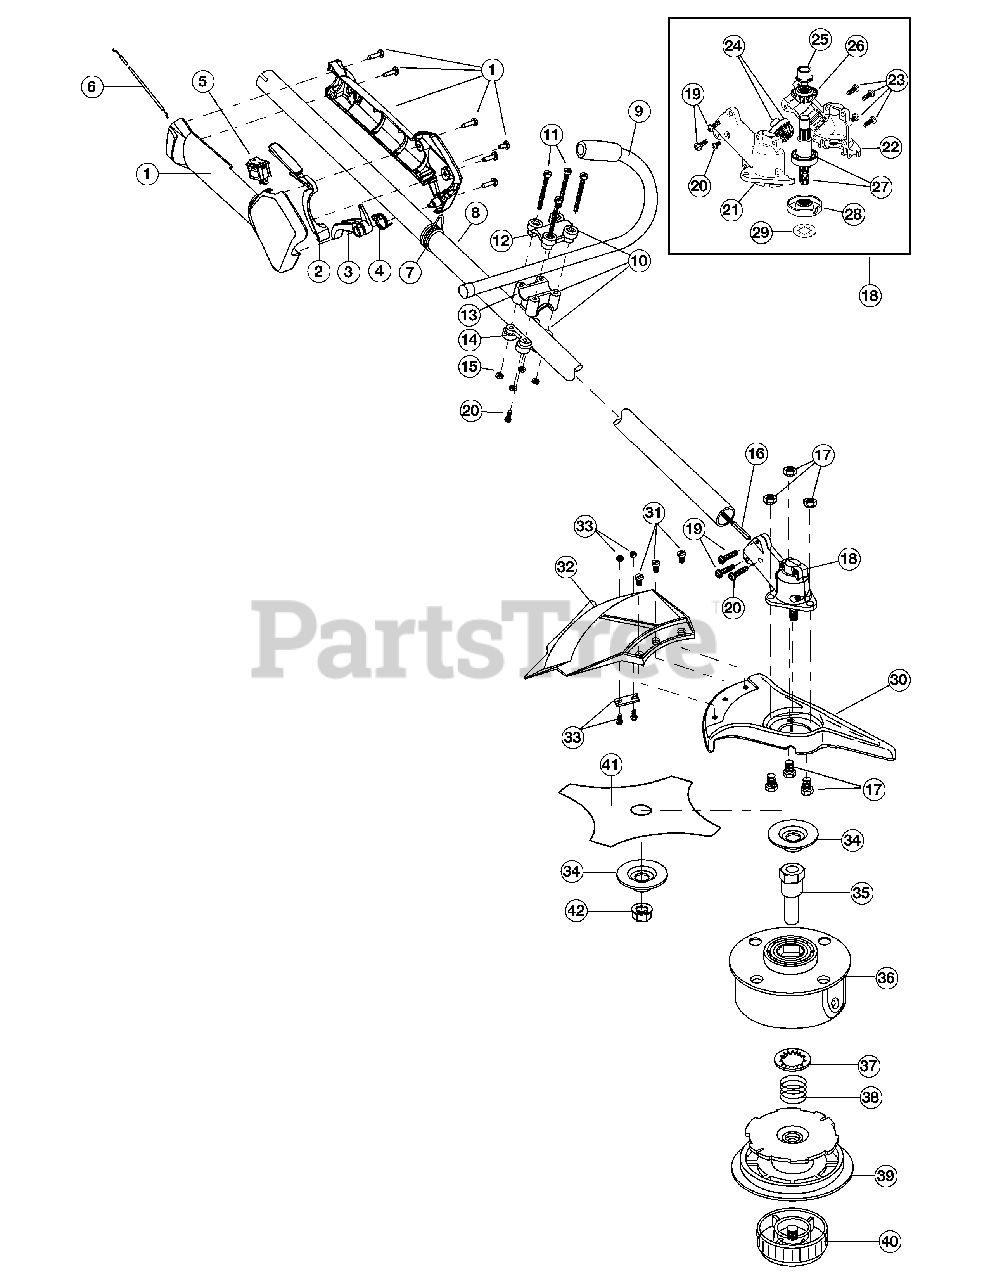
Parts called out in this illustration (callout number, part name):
1	Throttle Housing Assembly (includes 2-4)
2	Throttle Trigger Lock-Out
3	Throttle Trigger
4	Throttle Trigger Spring
5	Switch Assembly (includes 6)
6	Throttle Cable Assembly
7	Harness Clip
8	Upper Drive Shaft Housing Assembly
9	J-Handle Assembly
10	Handle Bracket Assembly (includes 13-15 & 20)
12	Upper Handle Clamp
13	Middle Handle Clamp
14	Lower Handle Clamp
16	Flexible Drive Shaft
17	Shield Mount Screw Assembly
18	2 piece Gearbox Assembly (includes 19-29)
19	Gearbox Mounting Hardware
20	Anti-Rotation Screw
21	Left Housing
22	Right Housing
23	Gear Box Screw
24	Pinion Gear Assembly
25	Output Shaft Bushing
26	Output Shaft Gear
27	Output Shaft Assembly (includes 25 & 26)
28	Blade Driver
29	Palnut
30	Blade Shield/Shield Mount
31	Shield Mounting Screw
32	Shield Assembly (includes 33)
33	Blade Assembly
34	Retaining Washer
35	Spool Shaft
36	Outer Spool Assembly
37	Retainer
38	Spring
39	Inner Reel
40	Bump Head Knob Assembly
41	4-Tooth Blade
42	Nut
